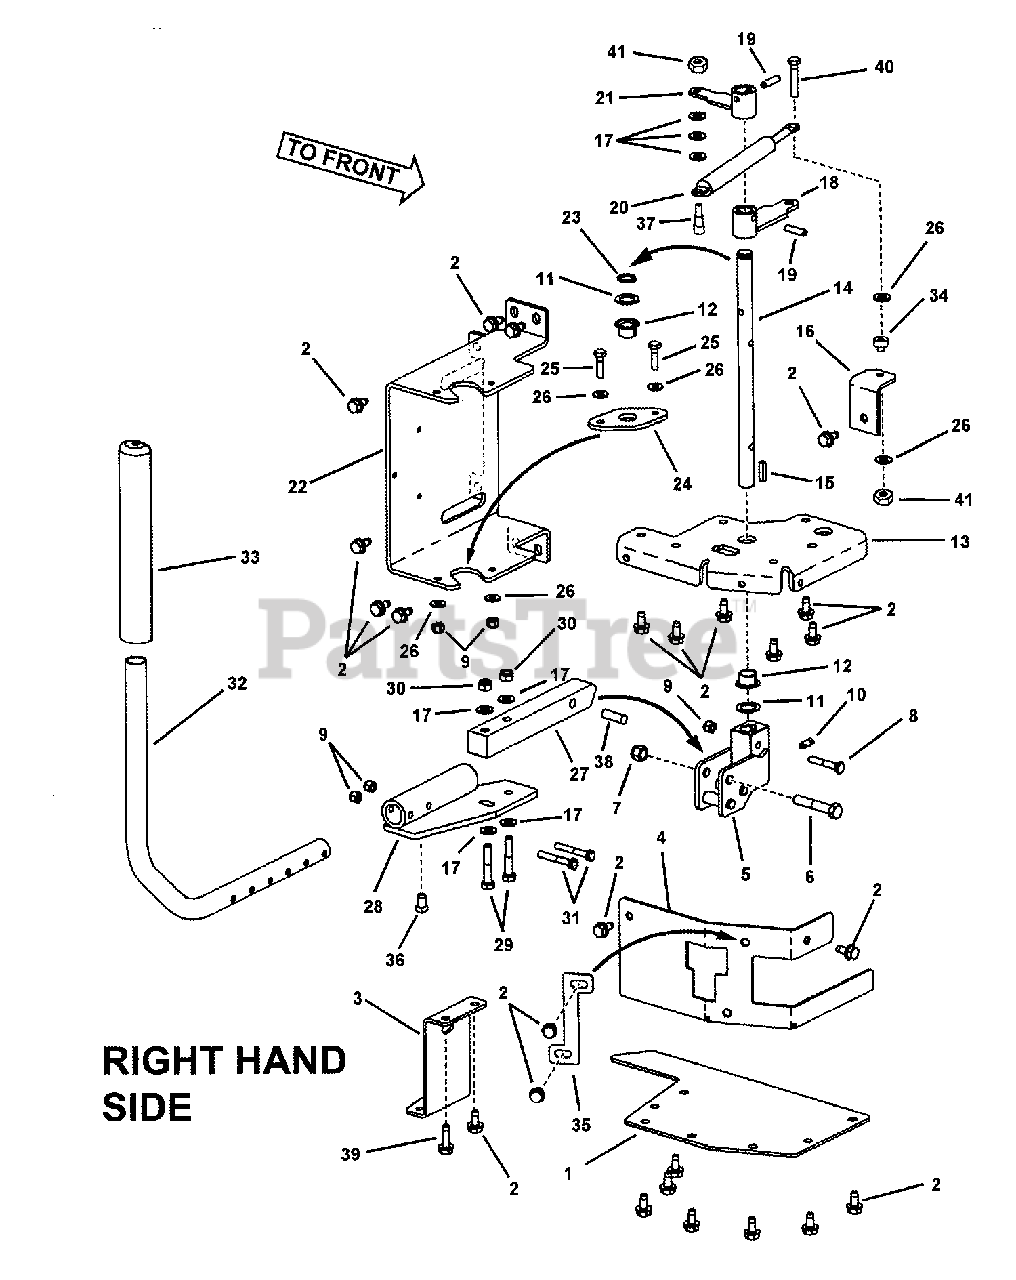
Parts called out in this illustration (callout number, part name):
1	LIMITER BRACKET, Right Hand Outside
2	SCREW, 5/16-18 x 5/8" Hex Washer Self-Tap
3	LIMITER BRACKET, Rear
4	LIMITER BRACKET, Right Hand
5	WELDMENT, Mounting Hub
6	BOLT, 3/8-16 X 2, GD5, CZ
7	NUT, 3/8-16 HEX NYLON LOCK
8	SCREW, 1/4-20 x 1-1/2" Hex Head Cap GR5
9	NUT, 1/4-20 HEX NYLON LOCK
10	SET SCREW, 5/16-18 Square Head w/Patch
11	WASHER, .64 I.D. x .99 O.D. x .05 Flat
12	BUSHING, Teflon Impregnated
13	BUSHING MOUNT PLATE, Right Hand
14	CROSSROD
15	KEY, 3/16" Square x 7/8" Long
16	BRACKET, Dampener Frame
17	WASHER, 5/16" Flat
18	WELDMENT, Bellcrank, Pump Control
19	GROOVE PIN, 1/4 x 1-1/4" long
20	CYLINDER, Dampener
21	WELDMENT, Bellcrank Dampener Control
22	CHANNEL, Mounting
23	RING, 5/8" External Retaining
24	MOUNTING PLATE, Left Hand Bearing
25	BOLT, 1/4-20 X 1" GD5 CZ
26	WASHER, .28 I.D. x .63 O.D. x .06 Thick Flat
27	MOUNTING ARM
28	WELDMENT, R.H. Adjustable Handlebar Attachment
29	BOLT, 5/16-18 X 1-3/4 GD5 YZ
30	NUT, 5/16-18 HEX NYLON LOCK
31	BOLT, 1/4-20 X 1-3/4" GD5 YZ
32	HANDLEBAR
33	GRIP, Twin Stick
34	SPACER
35	BRACKET, Speed Control
36	SET SCREW, 5/16-18 x 1/2" Square Head Cup Point w/patch
37	SCREW, 1/4-20 Shoulder Socket Head
38	SPACER, .498 O.D. x 1.010" long
39	SCREW, 5/16-18 x 1" Hex Washer Self-Tap
40	SCREW, 1/4-20 x 1-1/4" Hex Head Cap
41	NUT, 1/4-20 Hex Center Lock
